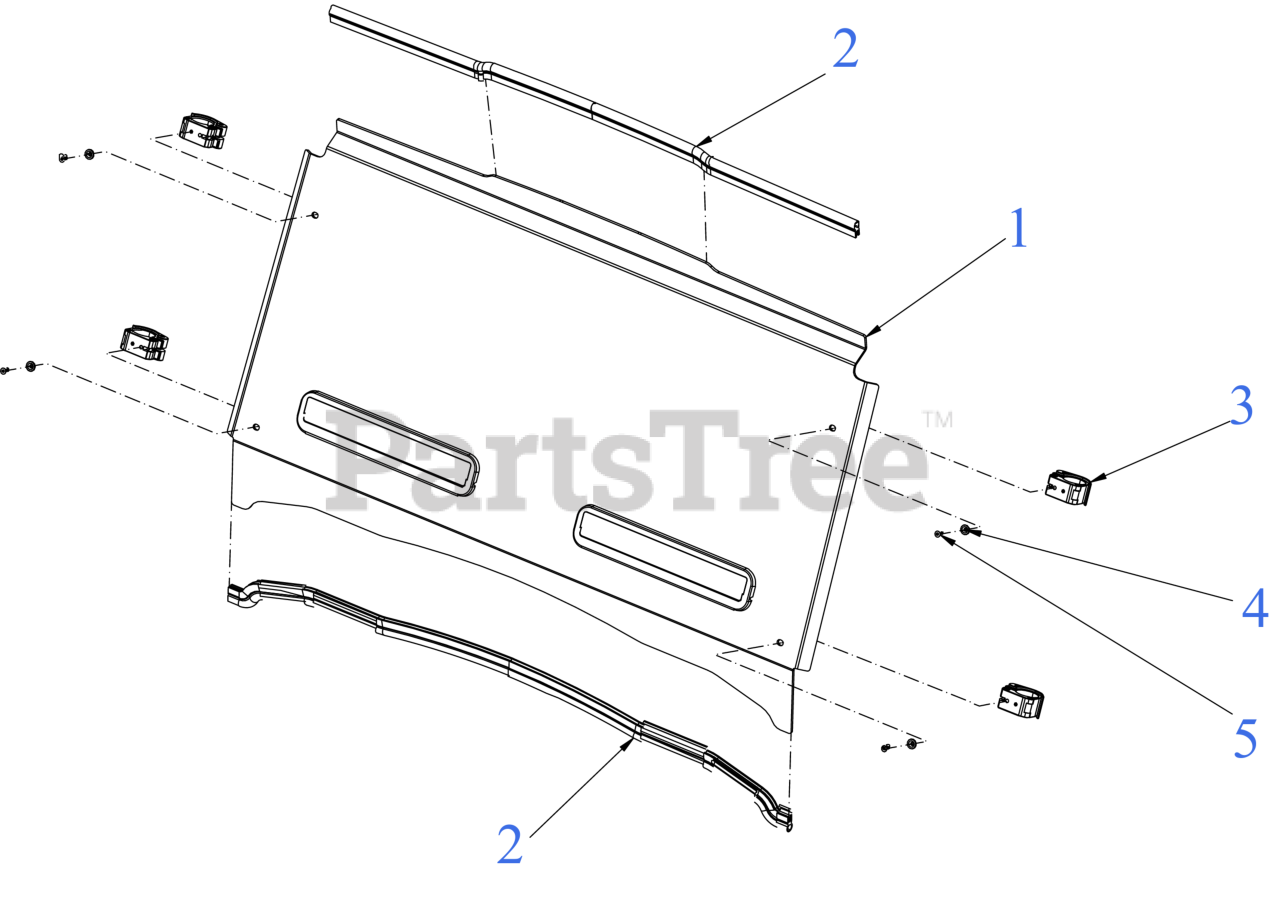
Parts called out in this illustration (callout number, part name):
1	WINDSHIELD W/ VENTS
2	BULB CHANNEL SEAL
5	BUTTON HEAD SCREW M6x16
